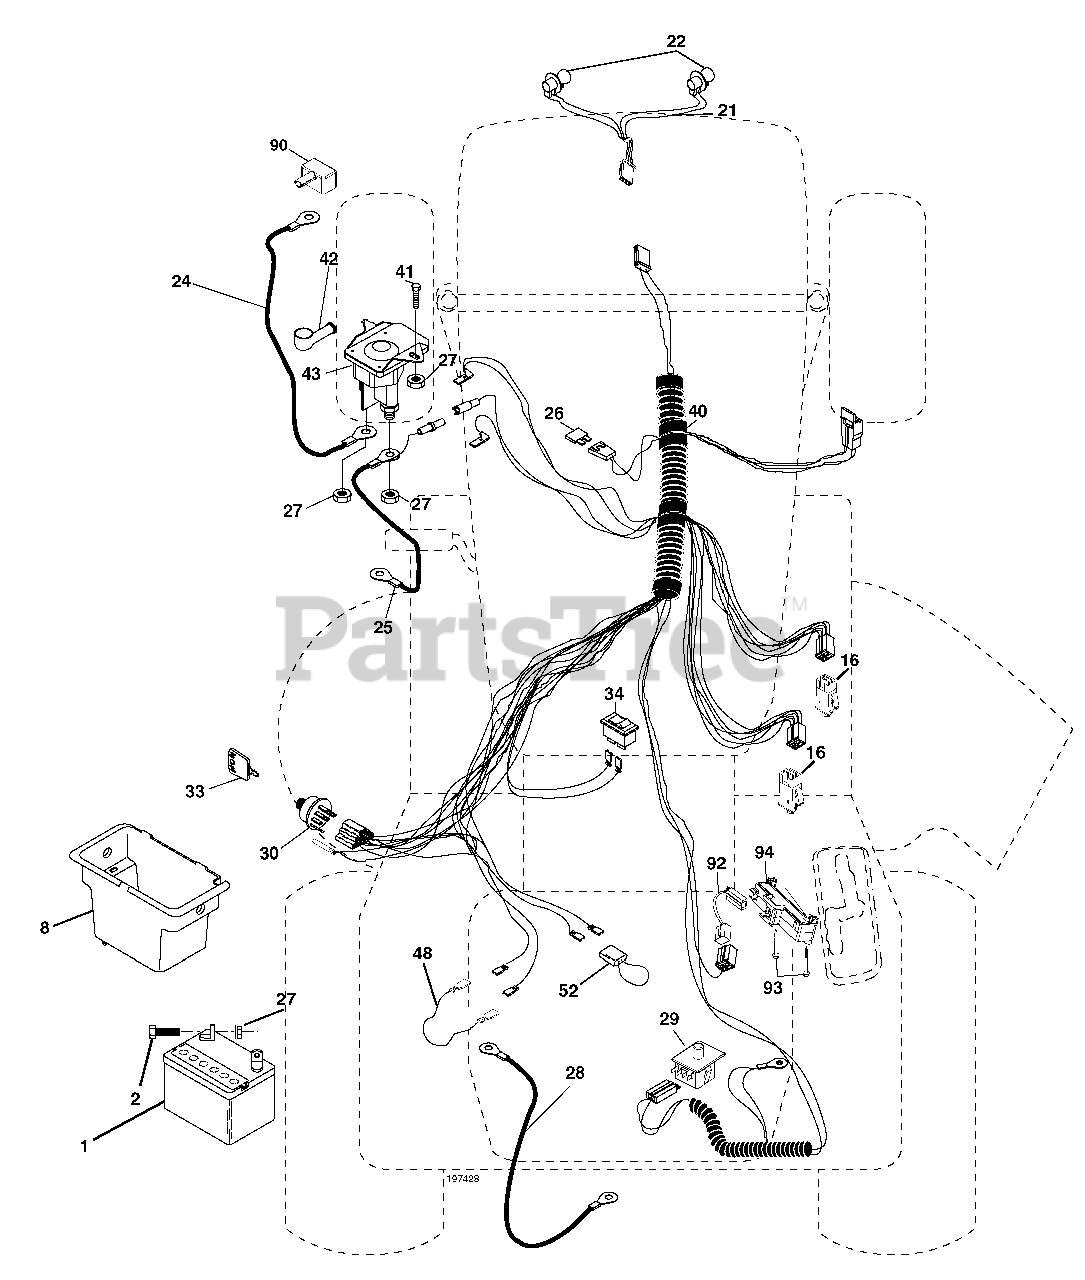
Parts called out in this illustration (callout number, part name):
1	Battery 12 Volt 25 Amp
2	Bolt Hex Hd 1/4-20 unc x 3/4
8	Box Battery
16	Switch Interlock Push -In
21	Harness Asm Light W/4152J
22	Bulb Light #1156
24	Cable Battery 6 Ga. 11”red
25	Cable Battery 6 Ga. w/16 wire,red
26	Fuse 20 AMP
27	Nut Keps Hex 1/4-20 unc
28	Cable Ground 6 Ga. 12” black
29	Switch Seat
30	Switch Ign
33	Key Ign
34	Switch Light/Reset
40	Harness Ign
41	Bolt Blk Fin Hex 1/4-20 x 1/2
42	Cover Terminal Red
43	Solenoid
48	Adapter Ammeter
52	Protection Wire Loop
90	Cover Terminal
92	Harness Pigtail Reverse Switch
93	Screw Plastite 10-14 x 2.0
94	Module Reverse ROS
